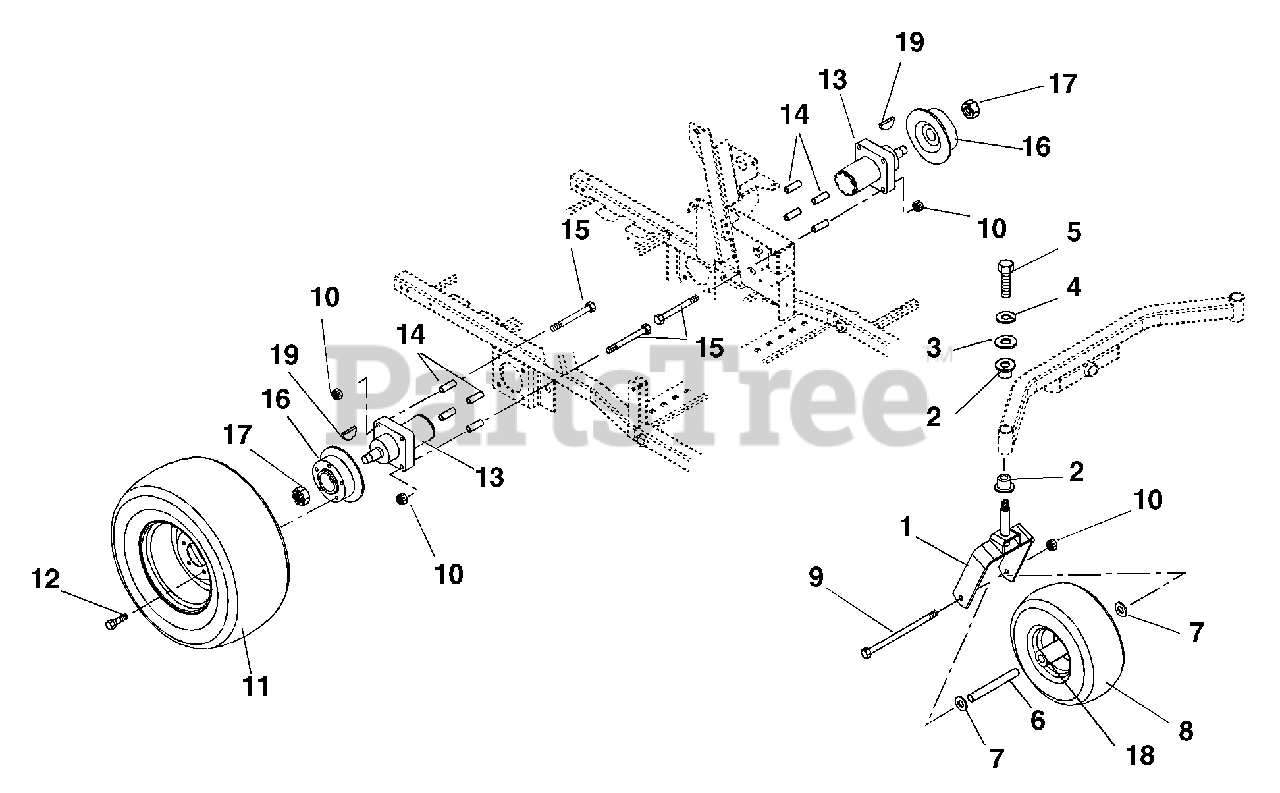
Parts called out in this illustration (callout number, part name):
1	WMT, FRONT FORK - ORANGE
2	BSHG-FLG1.020X1.385X.75X1.75NY
3	WSHR-FL-STL .380X1.50X.125YWZC
4	@WSHR-LK .38X.094 REG YWZC
5	@BLT-HEX .38-16X1.25 GR5 YWZC
6	SPACER - WHEEL
7	WSHR-FL-STL .515X1.625X.250 YZ
8	WHEEL/TIRE ASM
9	@BLT-HEX .50-13X9.00 GR5 YWZC
10	@NUT-LK-CTR .50-13 YWZC
11	WHL/TIRE 23X8.50-12 MULTITRAC
12	BLT-LUG .50-20X.75X1.62 PL
13	WHEEL MOTOR, MB15
14	BSHG-SLV .513X.748X1.93 YWZC
15	SCR-SKH .50-13X4.50
16	HUB & DISK (PARK) 8" 1/2 HOLE
17	NUT-LK-JAM-PTCH 1.00-20
18	BRG, 25MM ID X 52MM OD X 15MM
19	KEY-WDRF .31X1.00 SFT #B
